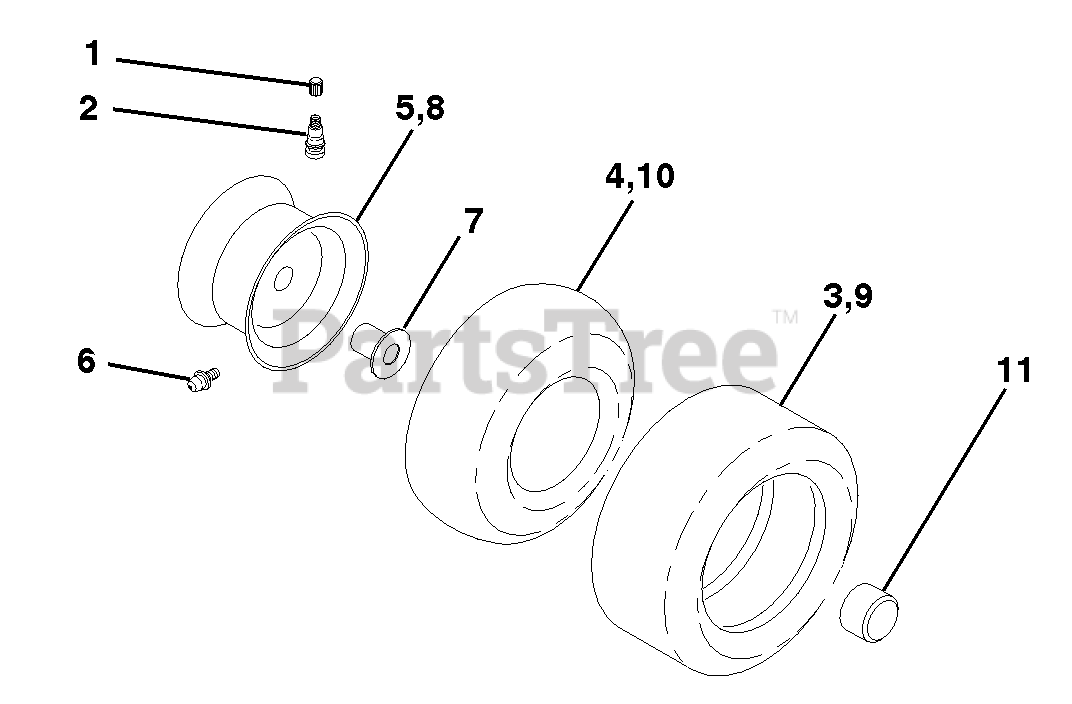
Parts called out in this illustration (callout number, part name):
1	Cap, Tire valve
2	Stem, Valve
3	Tire, Front
4	Tube, Front
5	Rim assembly, 6" front
6	Fitting, Grease
7	Bearing, Flange
8	Rim assembly, 8" rear
9	Tire, Rear
10	Tube, Rear
11	Cap, Hub Axle
